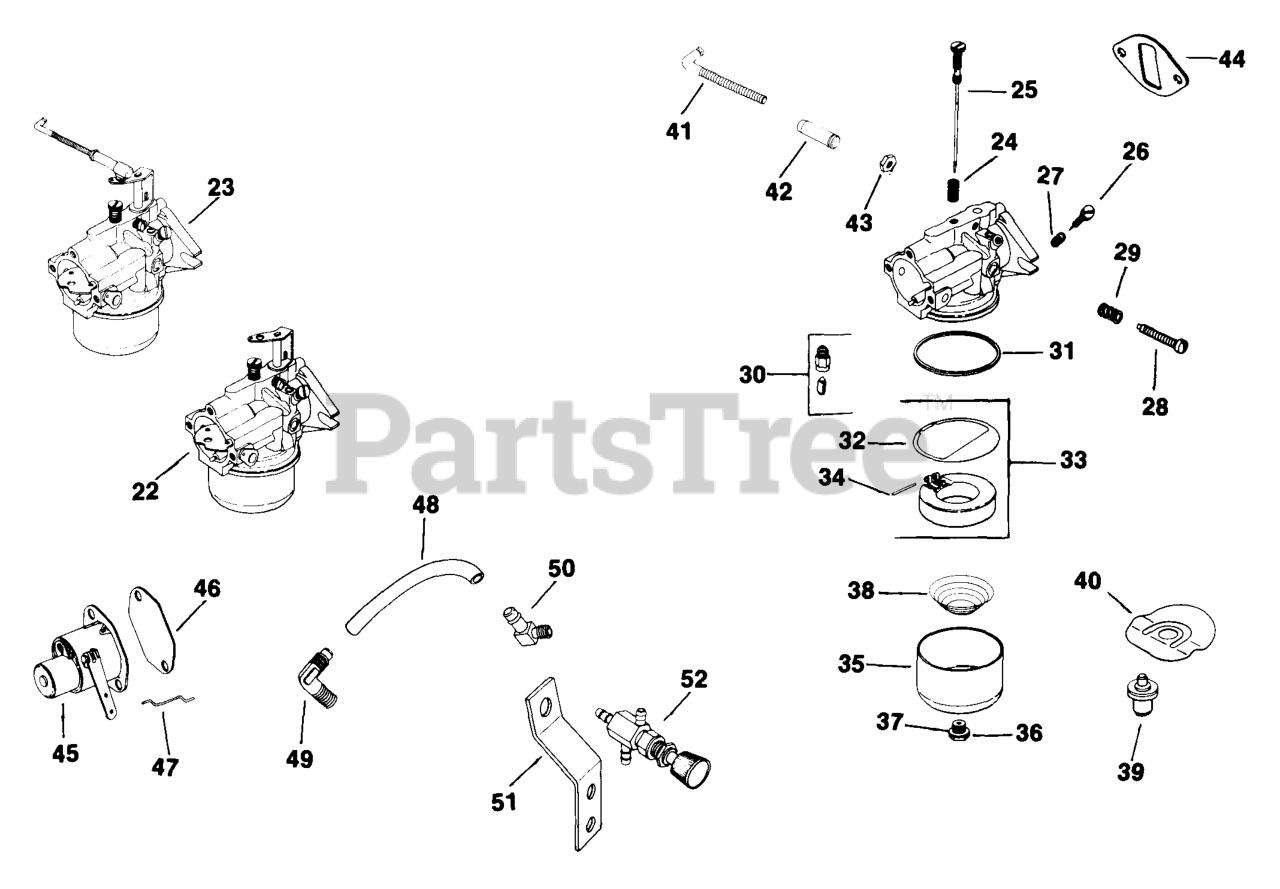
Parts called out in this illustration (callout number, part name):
23	CARBURETOR
25	NEEDLE - DISCONTINUED
27	SPRING-(#DSC)
28	SCREW, SPECIAL
30	Needle and seat
33	KIT, FLOAT REPAIR - DISCONTINUED
36	NUT - DISCONTINUED
41	ROD-(#DSC)
42	BODY - DISCONTINUED
43	NUT, MACH SCREW #10-32 GRD 2 USE 25 100 18-S
